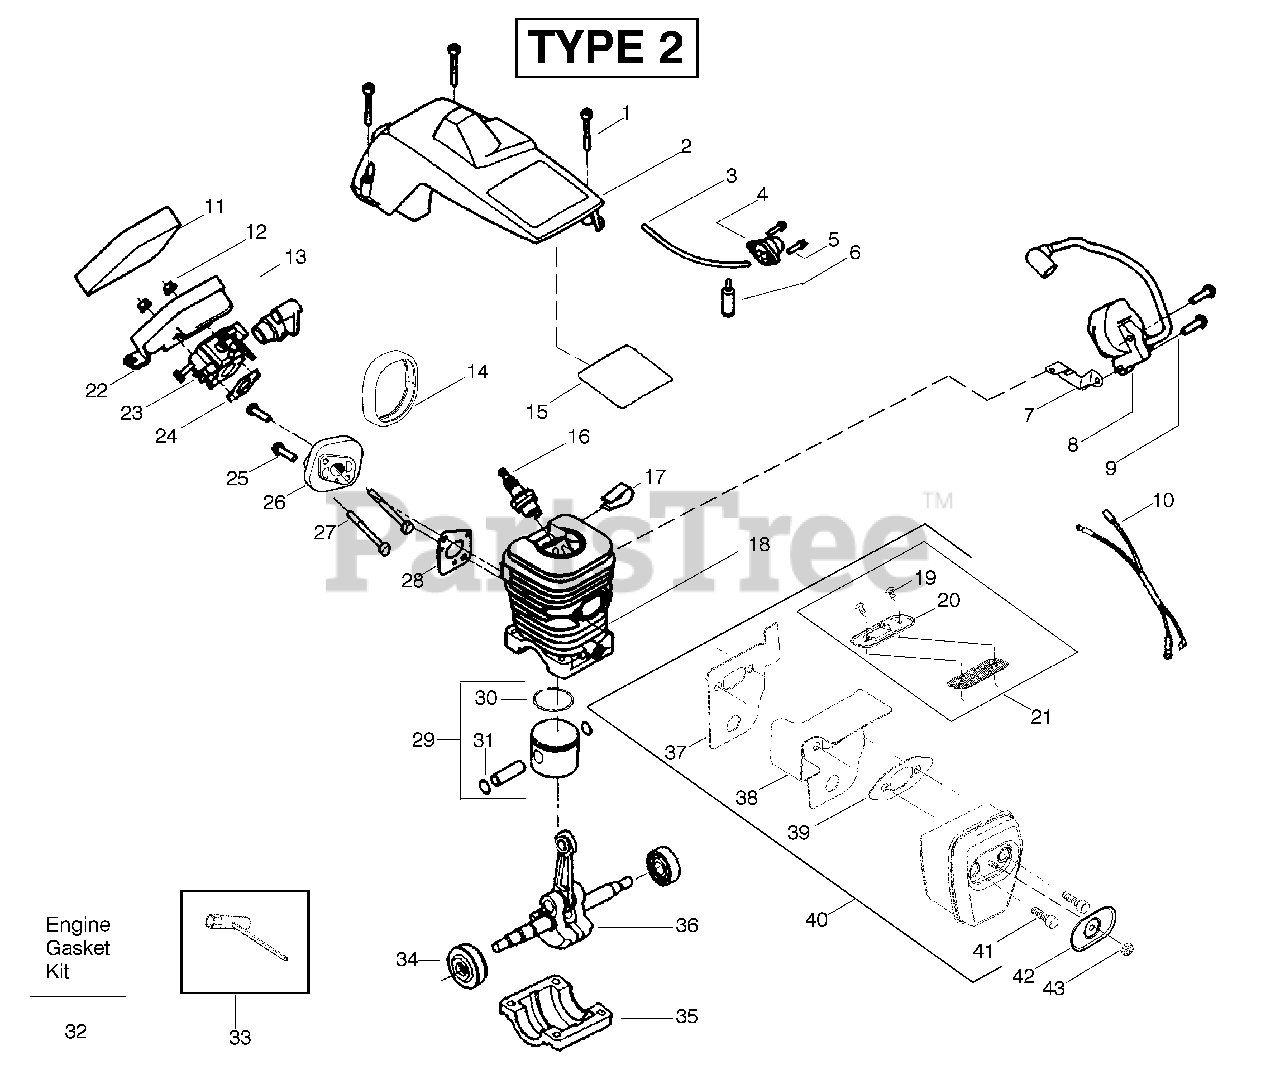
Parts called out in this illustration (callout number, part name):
2	Assy-Cylinder Shield
3	Kit-Fuel Line
4	Assy- Air Purge
6	Assy-Fuel Pick-up
7	Strap-Ground
8	Ignition Module
10	Assy-Wire Harness
11	Foam- Air Filter
13	Grommet-Carb Adjust
14	Seal-Carb Adapter
15	Reflector-Heat
16	Spark Plug
17	Clip-High Tension Lead
18	Cylinder
19	Screw-Outlet cover
20	Cover - Outlet
21	Kit-Spark Arrestor
22	Air Filter Housing
23	Kit-Carburetor (Walbro-WT-89)
24	Gasket-Carb.
26	Carb. Adapter
28	Gasket- Adaptor
29	Kit-Piston
30	Ring-Piston
31	Retainer-Piston Pin
32	Kit-Engine Gasket
33	Bar Wrench
34	Assy-Seal & Bearing
35	Cap-Crankcase
36	Assy-Crankshaft
37	Backplate
38	Guide-Outlet
39	Gasket-Muffler
40	Assy-Muffler
41	Bolt-Muffler
42	Cover-Bolt
43	Nut-Brass
